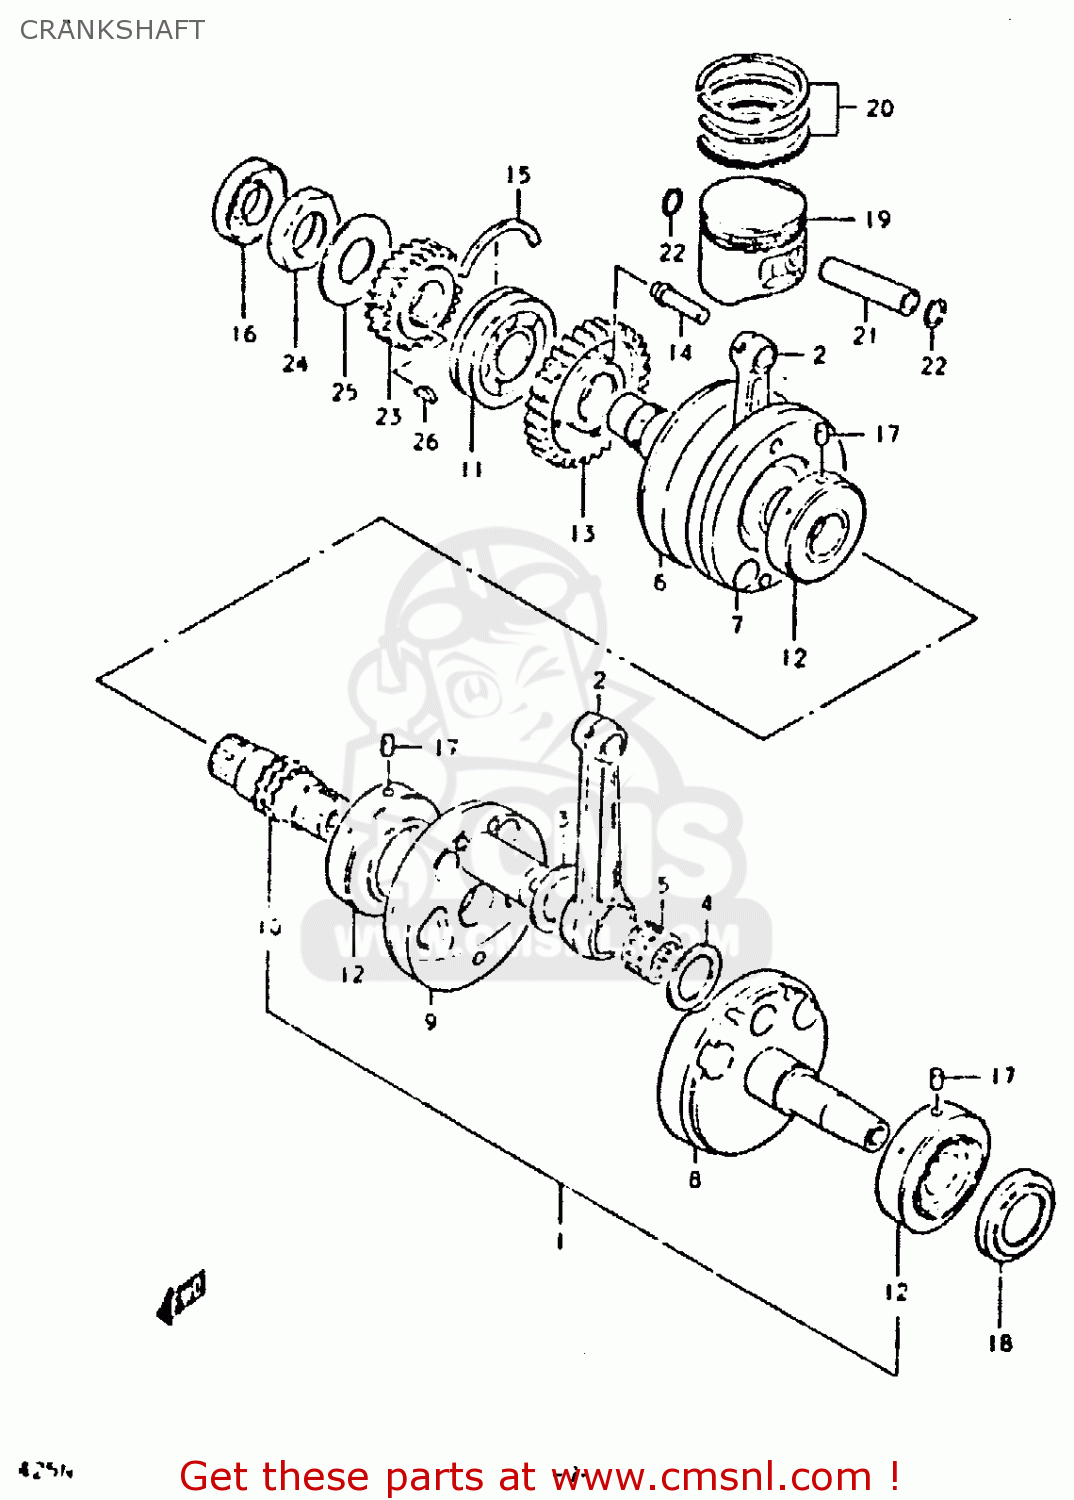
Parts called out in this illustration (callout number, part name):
1	CRANKSHAFT ASSEMBLY
2	ROD,CONNECTING
3	WASHER (28X48X2)
4	WASHER(28X48X1)
5	BEARING(28X38X19.8)
6	CRANKSHAFT
7	WEB,CRANK
8	CRANKSHAFT,LEFT
9	WEB,CRANK
10	SHAFT,TIMING CHAIN DRIVE
11	BEARING(30X72X19)
12	BEARING
13	GEAR,CRANK BALANCER DRIVE
14	PIN
15	C RING
16	SEAL,OIL(25X47X8)
17	PIN
18	OIL SEAL
19	PISTON (67.00MM)
20	RING SET,PISTON
21	PIN,PISTON
22	CIRCLIP
23	GEAR,PRIMARY DRIVE
24	NUT
25	WASHER
26	KEY
